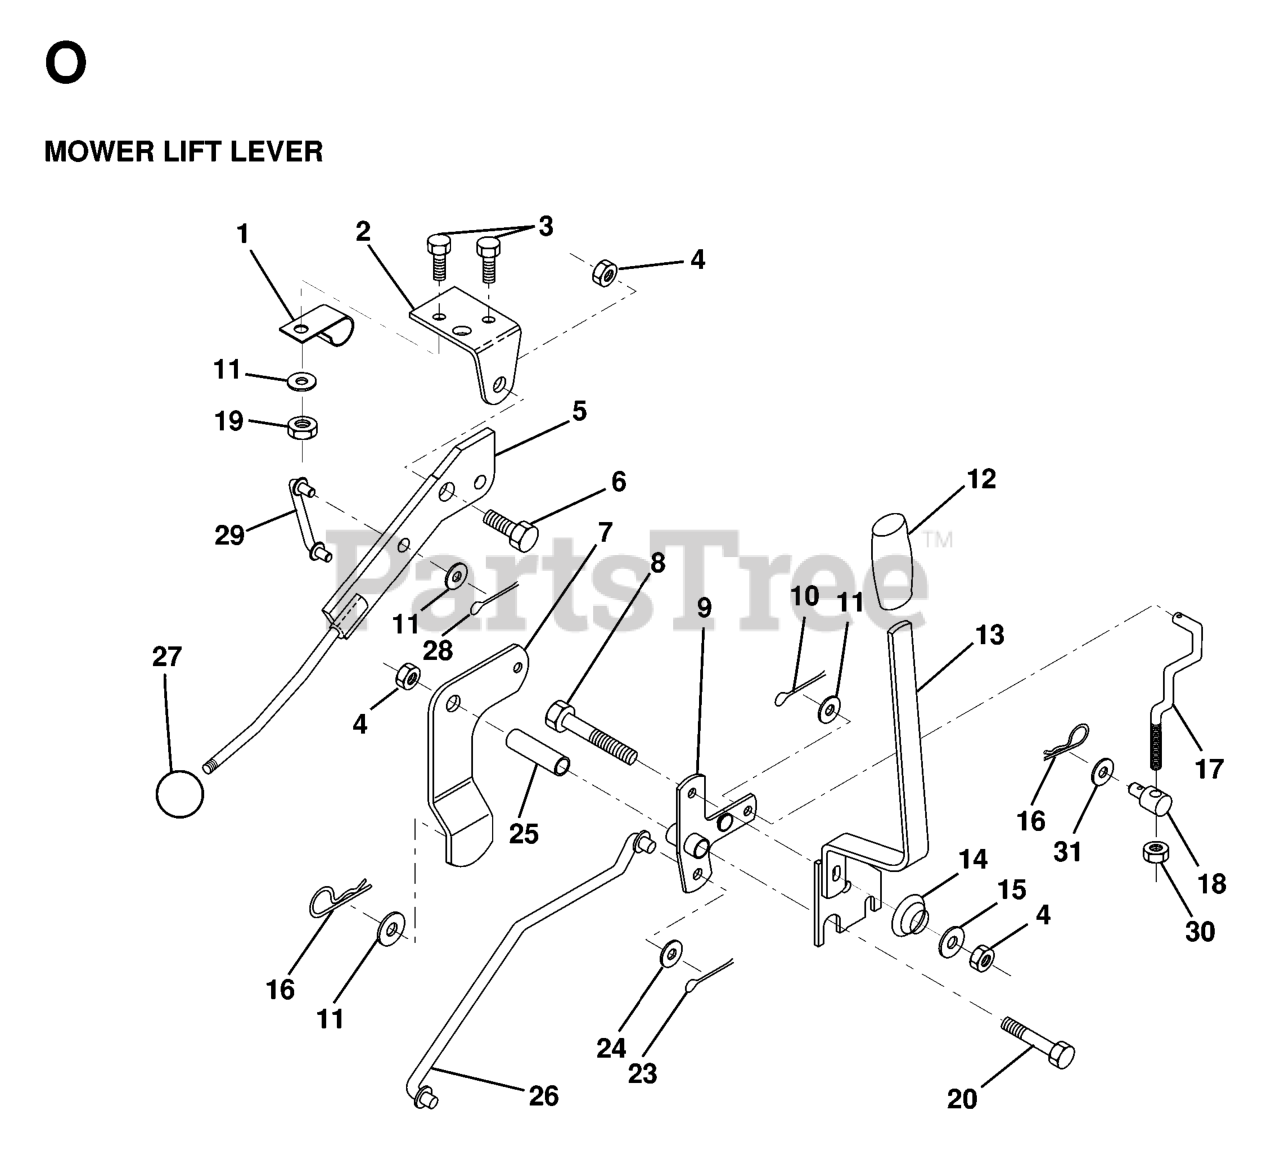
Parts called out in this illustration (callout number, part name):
1	CLIP,INSULATOR
2	BRKT CLUTCH
3	BOLT
5	CLUTCH LEVER
6	BOLT, SHOULDER LT
7	ASSEMBLY MOWER CLUTCH ARM
9	BELLCRANK,LIFT
10	COTTER PIN
11	WASHER
12	HANDLE GRIP
13	LIFT HANDLE ASSY
14	SPRING COMPRESSIO
15	WASHER T
16	SPRING TI
17	LINK LIFT FRT
18	TRUNNION.ADJUSTABLE.3/8-16
19	Nut, Keps Blk Hex 1/4-20 UNC
23	PIN COTTER
24	WASHER GT
25	TUBE SPACER
27	KNOB T (3/8 HOLE)
28	COTTER PIN
29	LINK MOWER CLUTCH
30	NUT
31	WASHER
